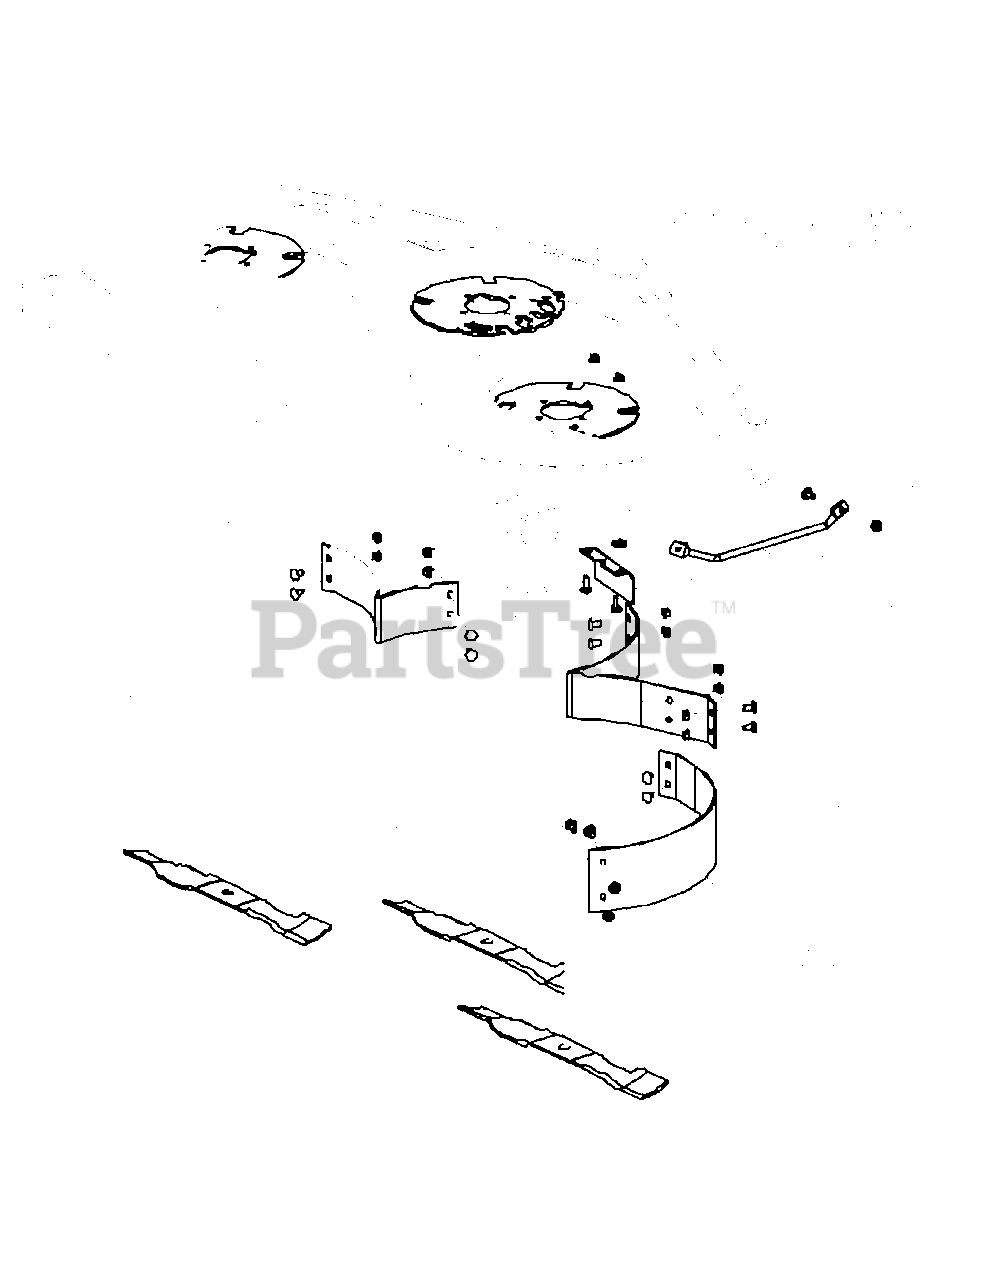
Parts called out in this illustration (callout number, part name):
1	NUT, HEX 3/8-16 FLG LOCK
2	WASHER, IDLER
3	BOLT, CARR 3/8-16 X .75 LG
4	BOLT, CARR 3/8-16 X 1.0 LG
9	BRKT, CHUTE, FAB DECK
10	GUARD, FINGER, FAB DECK
11	Baffle, MULCH, FAB 60 LH
12	Baffle, MULCH, FAB 60 CENTER
13	Baffle, MULCH, FAB 60 RH
15	BLADE, 21.0, MULCH, 0.756 ID
